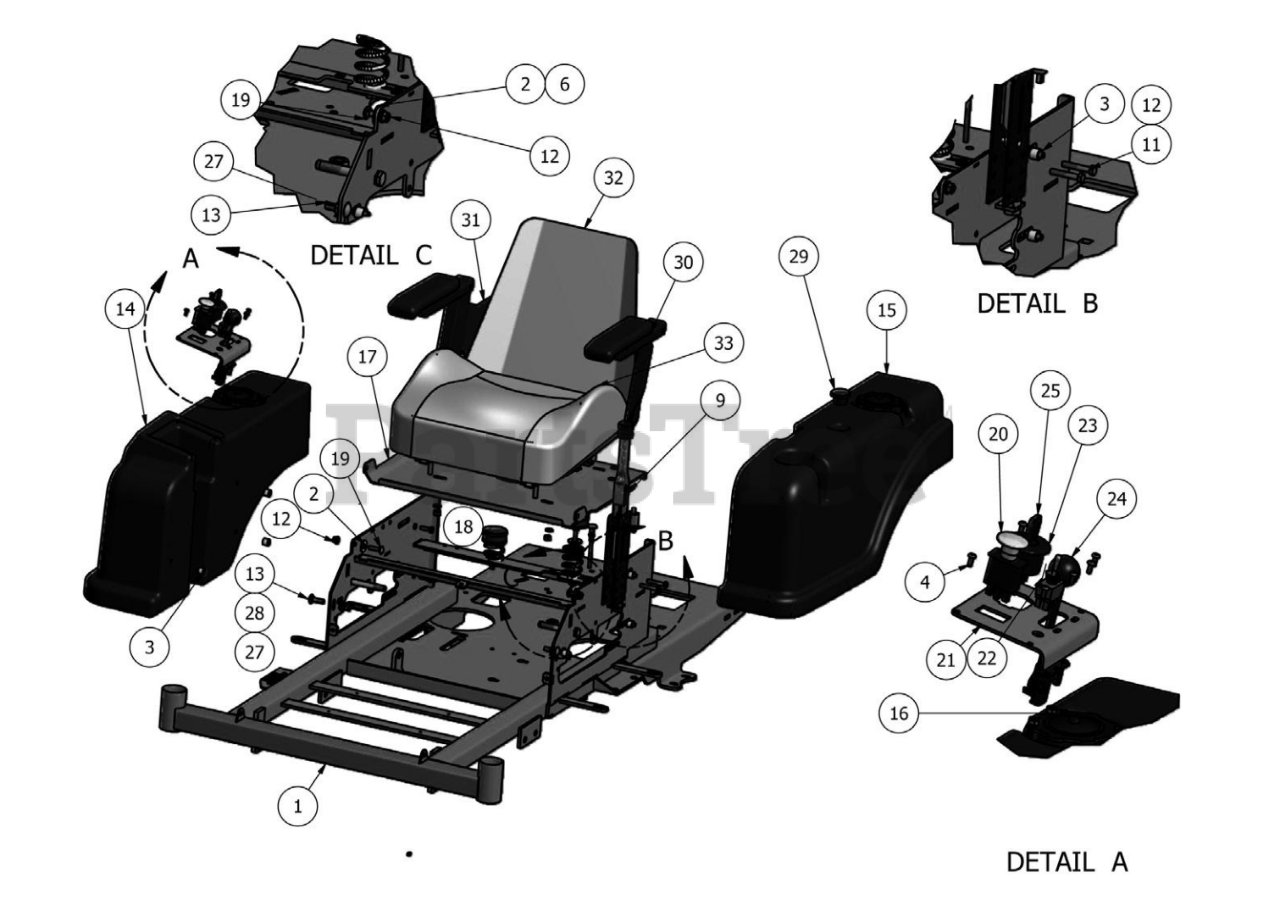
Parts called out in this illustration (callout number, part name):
2	.360 x .983 x .120 Nylon Washer
3	.360 x .735 x .585
4	10-24 x 5/8 Button Socket
6	3/8 Washer
9	Brake Handle Kit
11	5/16" x 1 3/4" Hex Bolt
12	5/16" Flange Nut
13	3/8" x 1 1/4" Carriage Bolt
14	Fuel Tank - Right
15	Fuel Tank Left -
17	Seat Plate
18	Spring Cap Cover
19	5/16" x 1 1/4" Carriage Bolt
20	PTO Engager
21	Control Panel
22	Joystick - Deck Lift
23	Ignition Switch
25	Ignition Key
27	3/8" Hex Nut
28	3/8" Flat Washer
29	Fuel Gauge and Grommet
30	Arm Rest Cushion
32	Backrest Cushion
33	Seat Cushion
